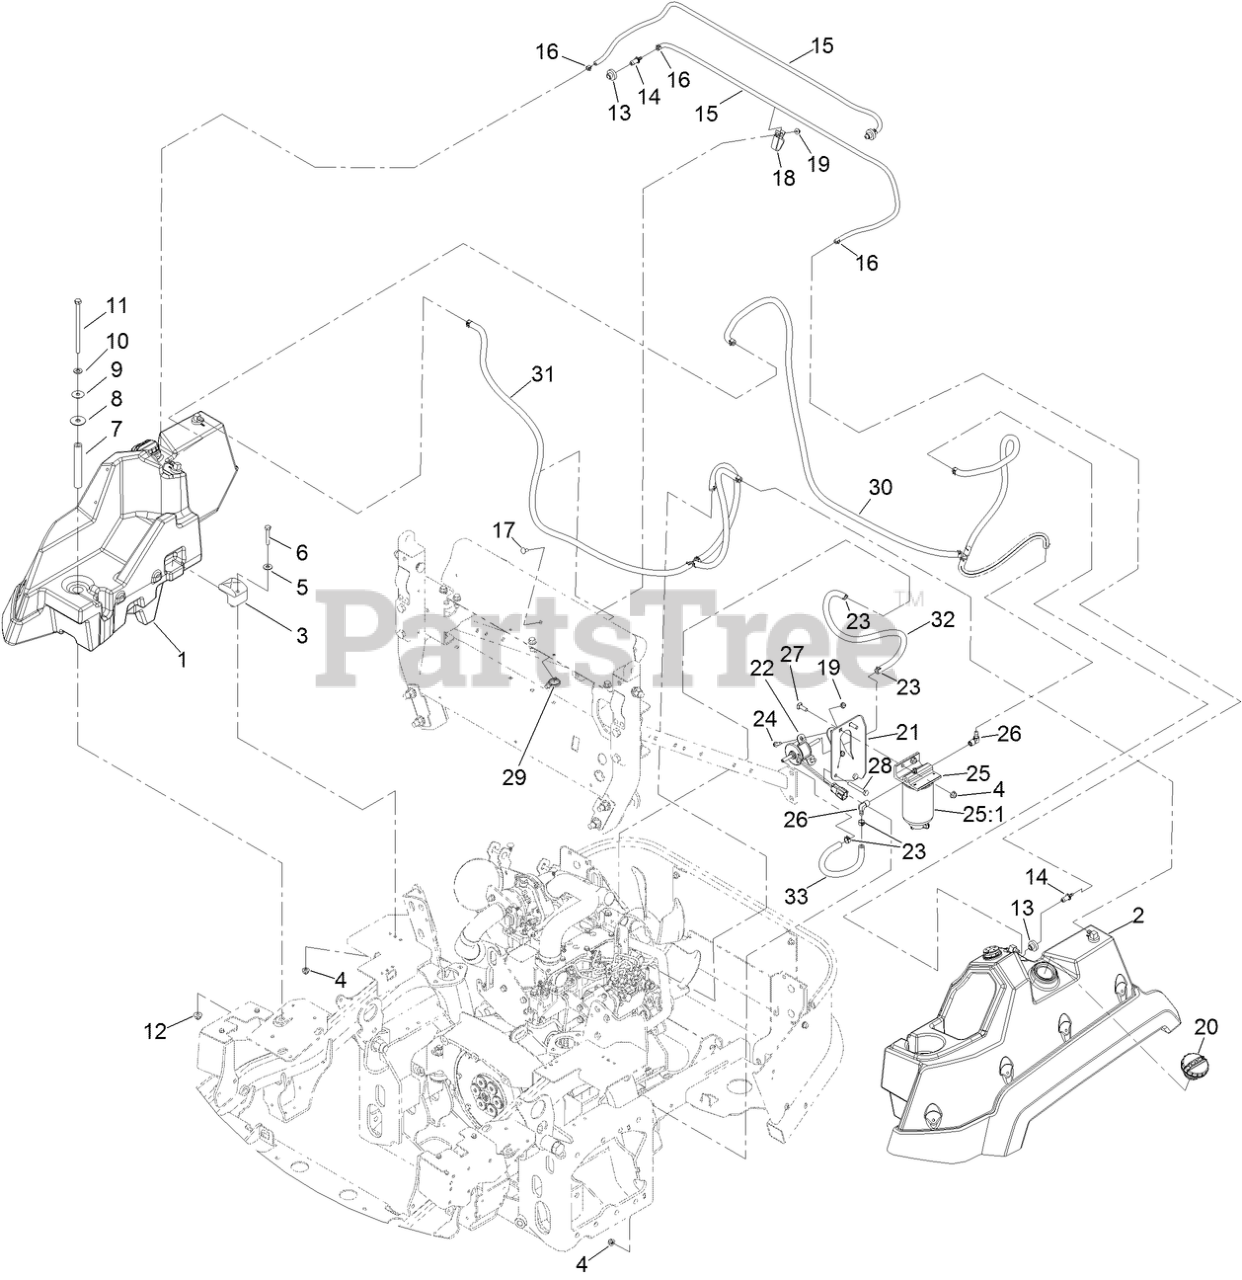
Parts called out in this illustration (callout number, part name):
1	RH FUEL TANK ASM
2	LH FUEL TANK ASM
4	NUT-HF, NI
5	WASHER-FLAT
6	SCREW-HH
7	TUBE-SPACER
8	WASHER-RUBBER
9	WASHER-PLAIN
10	WASHER-FLAT
11	SCREW-HH
12	NUT-HF, NI
13	BUSHING
14	FITTING-ORIFICE, STRAIGHT
15	HOSE-VENT, TANK
16	CLAMP-HOSE
17	SCREW-CARR
18	CLAMP-HOSE
19	NUT-HF
20	CAP-FUEL, DIESEL
21	BRACKET-FILTER AND PUMP, FUEL
22	PUMP-FUEL, ELECTRIC
23	CLAMP-HOSE
24	SCREW-HWH
25	SEPARATOR-FILTER
25:1	FILTER-SPIN ON
26	FITTING-HYD, 90
27	SCREW-CARR
28	SCREW-HH
29	CLIP-TIE
30	LINE-FUEL, SUCTION
31	LINE-FUEL, RETURN
32	HOSE-FUEL
33	HOSE-FUEL
